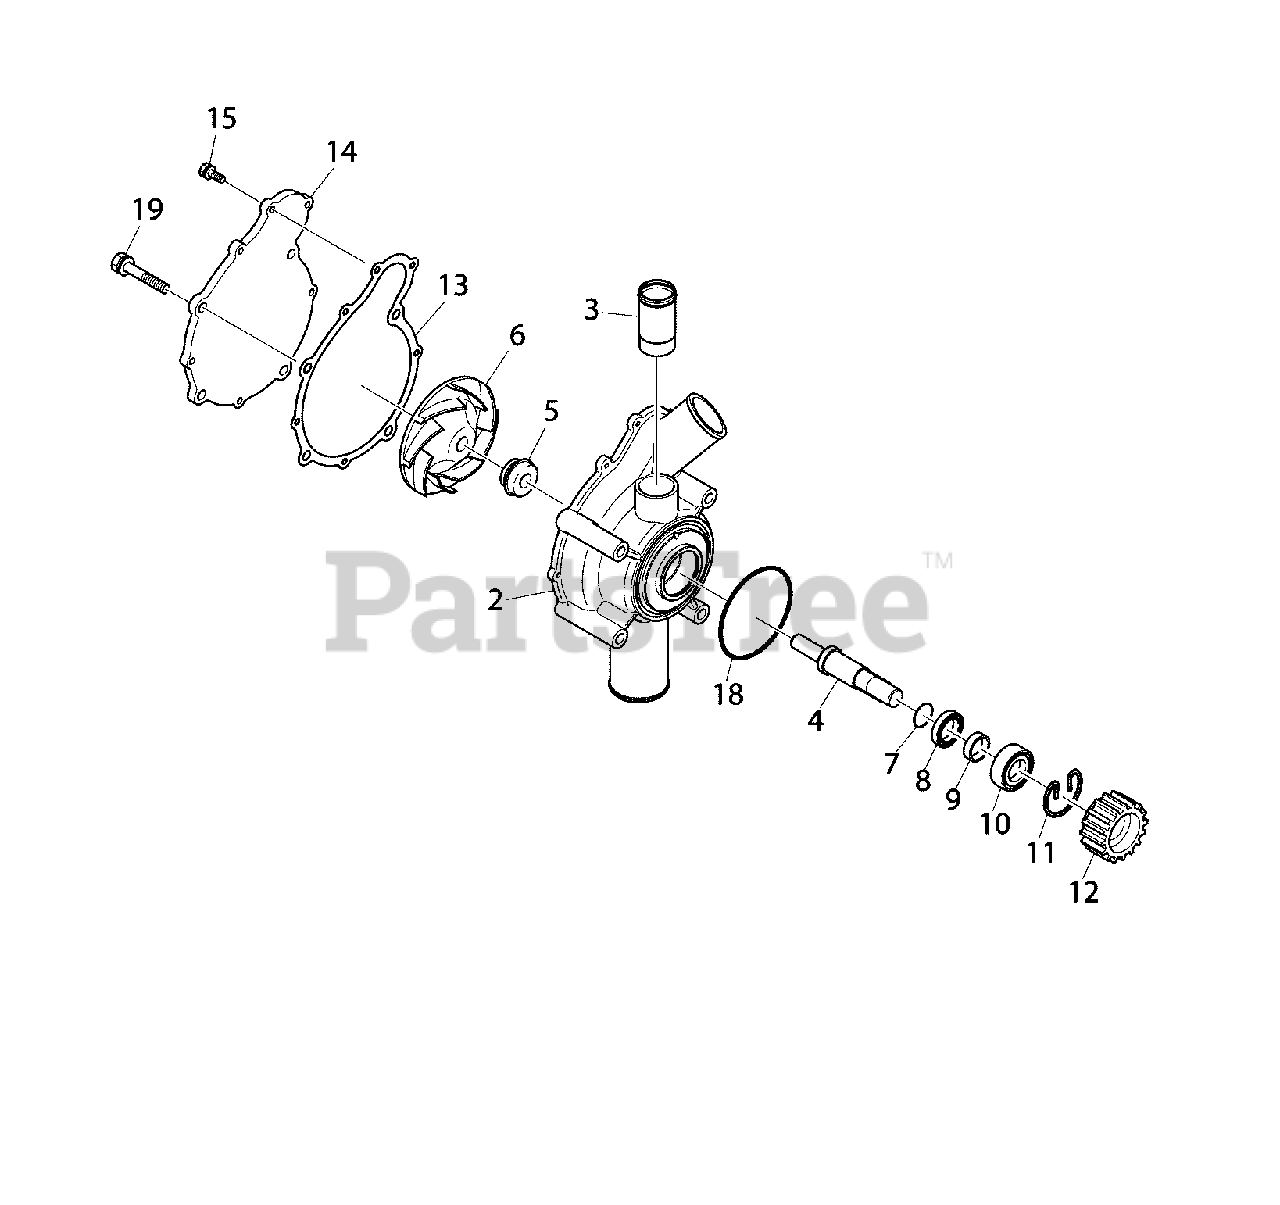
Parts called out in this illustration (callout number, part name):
1	PUMP, WATER
2	* HOUSING
3	* PIPE, WATER COOL
4	* SHAFT, W/PUMP
5	* SEAL, WATER PUMP
6	* IMPELLER, W/PUMP
7	* SEAL, OIL
8	* BEARING, BALL
9	* SPACER
10	* BEARING, W/PUMP
11	* RING, SNAP
12	* GEAR, W/P DRIVE
13	* GASKET, W/PUMP
14	* COVER, W/PUMP
15	* BOLT
18	* O-RING
19	* BOLT
